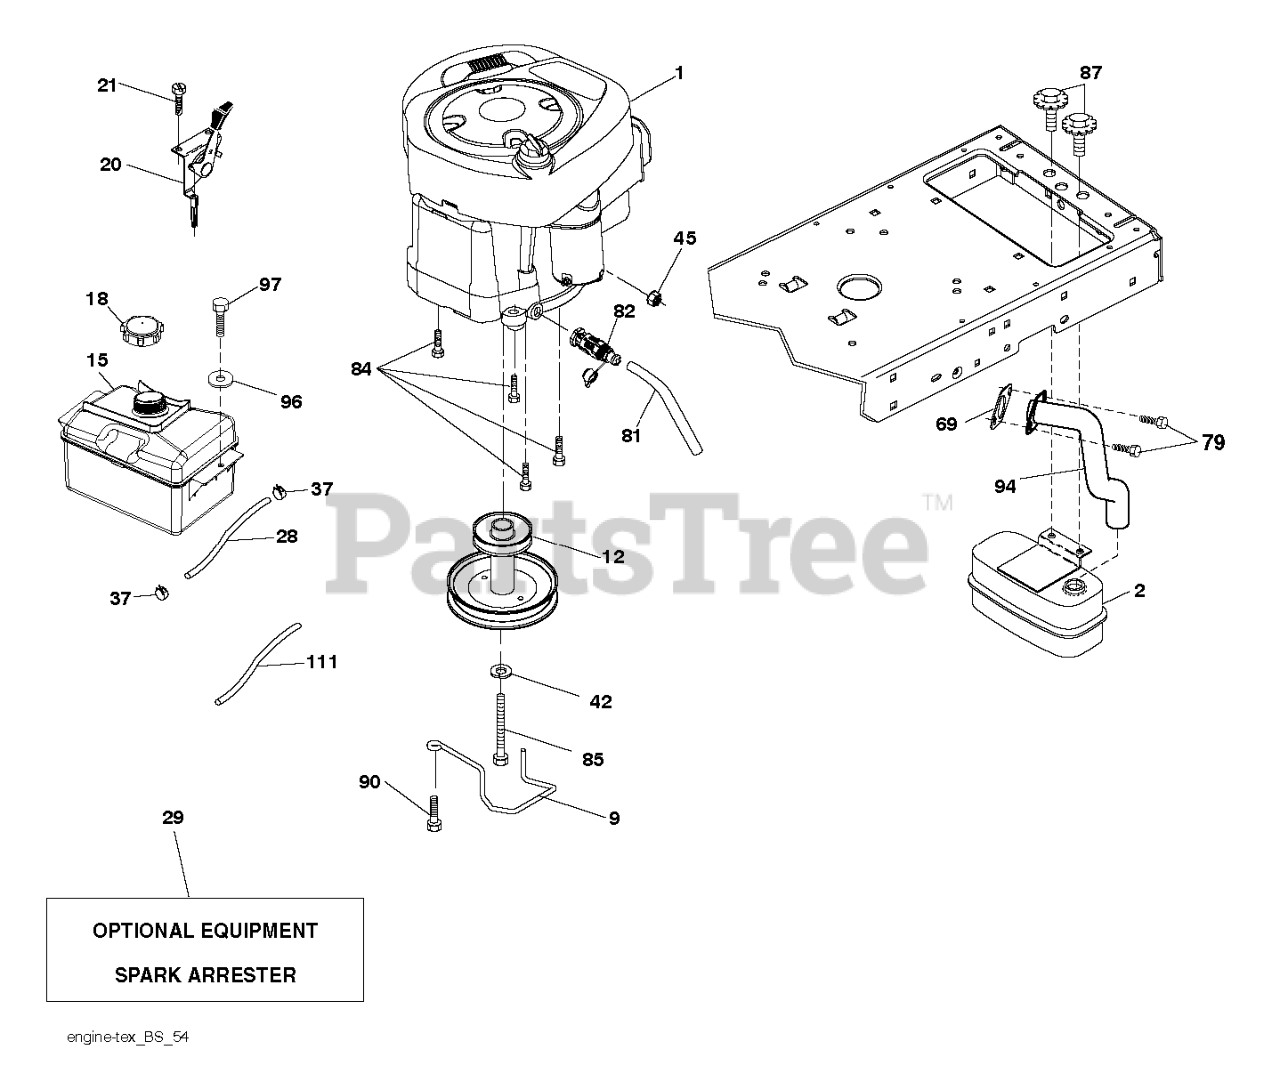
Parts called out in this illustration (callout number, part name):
2	MUFFLER.SINGLE.CYL.KOHL/B&S
9	KEEPER.BELT.ENGINE.4.2
12	PULLY ENGINE
15	TANK.ASM.FRT.2.5 GAL.W/CAP.EPA
18	CAP.2.25'.VENTED.TETHER .EPA
20	CONTROL.TH/CK.COBRA.KO
21	SCREW.#10 X 0.750.BOS
28	LINE.FUEL.20"FRONT.EMI
29	KIT.SPARK ARRESTOR 794945 B&S
37	HOSE CLAMP
42	LOCKWASHER
45	NUT
69	REPL BY 532 27 22-93
79	SCREW.SOCKET HD.5/16-1
81	TUBE, DRAIN OIL ASM.
82	VALUE.OIL.DRAIN
84	SCREW.3/8-16
85	BOLT HEX 7/16-20X4-1/4"
87	BOLT.5/16-18UNCX3/4 W/SEMS.BLK
90	SCREW 3/8-16X1
94	EXHAUST.TUBE.B&S.28/31
97	SCREW HEXWSHR 1/4-20X3/4
111	RP PURGE LINE
